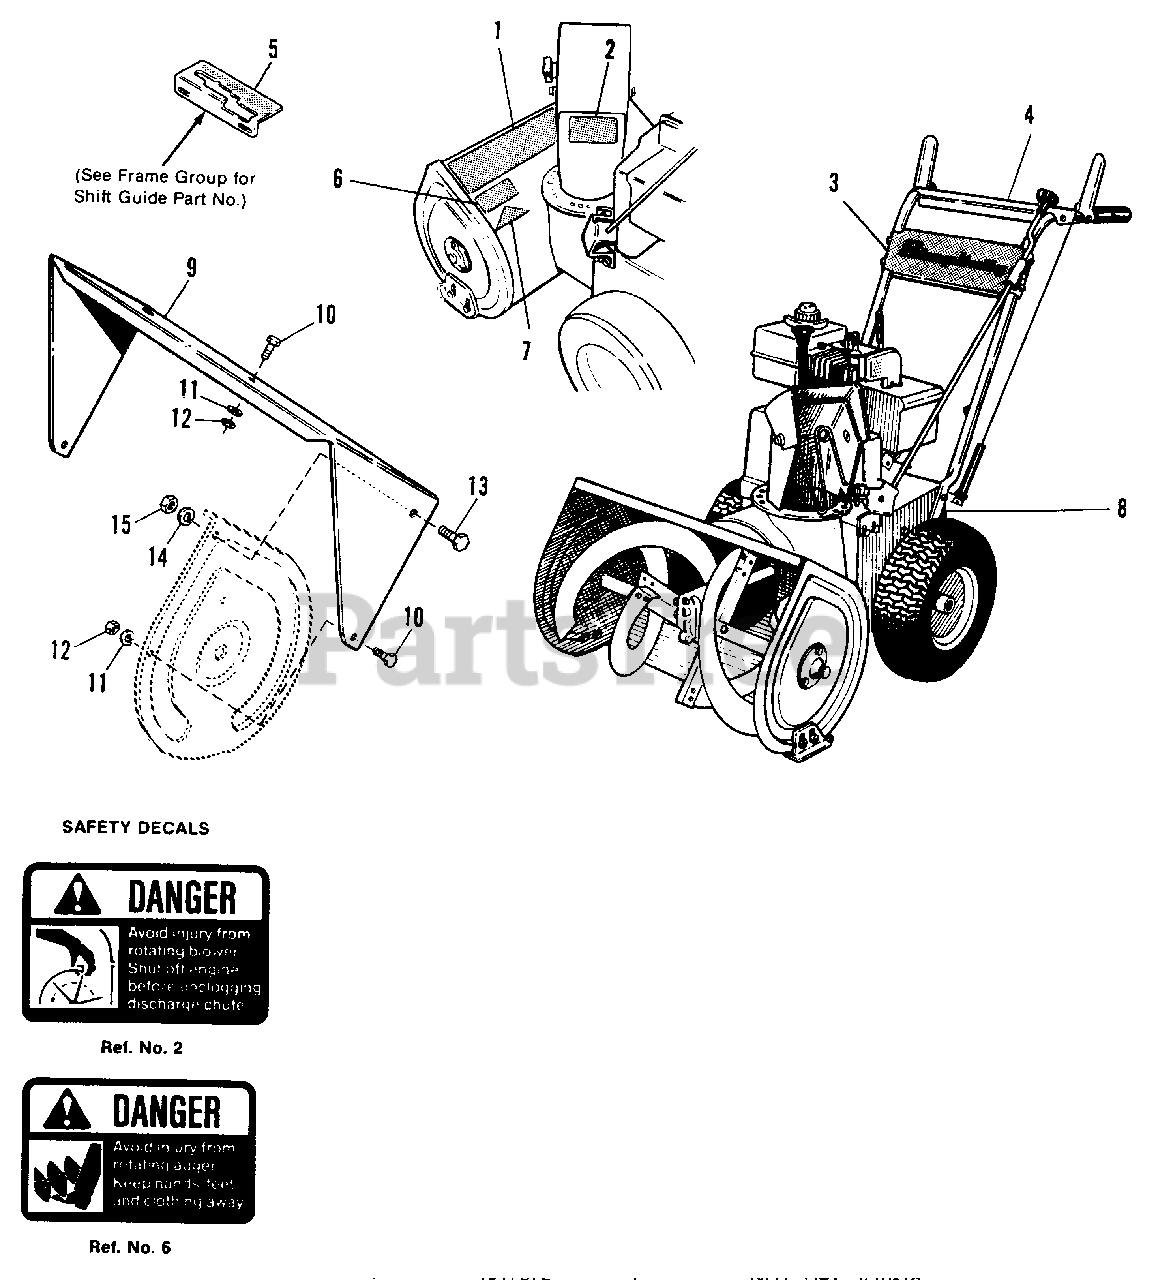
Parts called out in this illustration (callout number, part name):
1	DECAL, Simplicity 555
1	DECAL, Simplicity 755
2	DECAL, Danger, Blower
3	DECAL, Simplicity
4	DECAL, Dash
5	DECAL, Shift Pattern
6	DECAL, Danger, Auger
7	DECAL, OPEI
8	I.D. PLATE, Simplicity
9	WRAPPER EXT.
10	CAPSCREW, 1/4-20 x 1/2
11	LOCKWASHER, 1/4
12	NUT, Hex, 1/4-20
13	CAPSCREW, 5/16-18 x 5/8
14	LOCKWASHER, 5/16
15	NUT, Hex, 5/16-18
